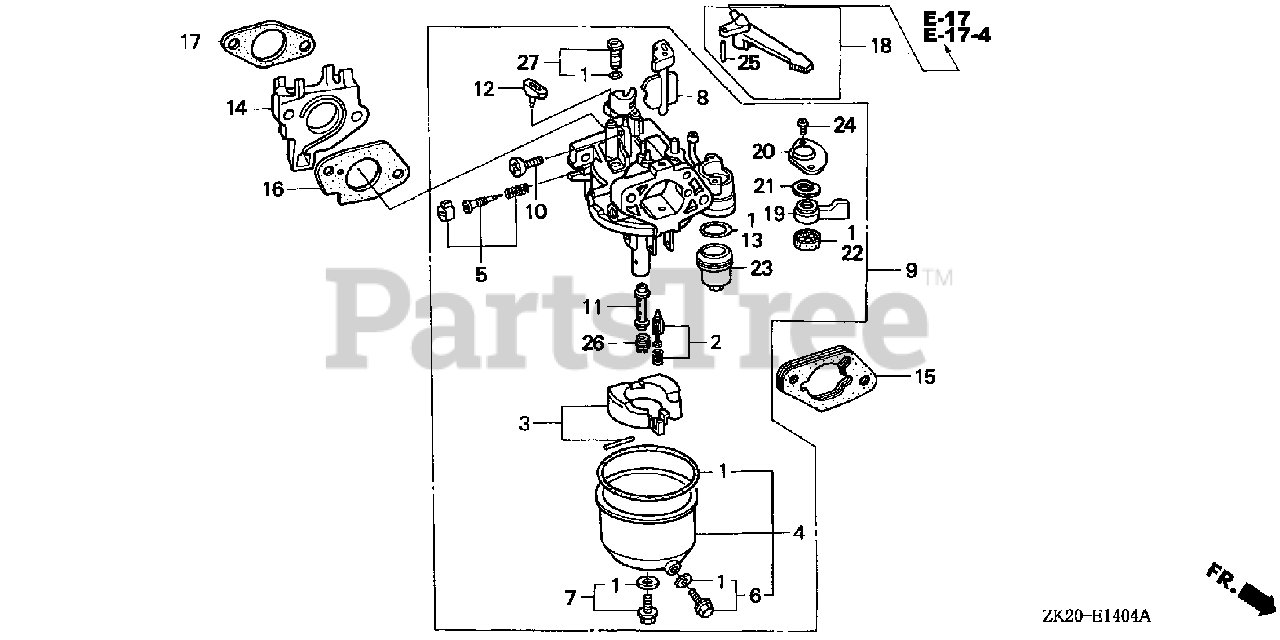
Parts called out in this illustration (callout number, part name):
1	GASKET SET
2	VALVE SET, FLOAT
3	FLOAT SET
4	CHAMBER SET, FLOAT
5	SCREW SET
6	SCREW SET, DRAIN
7	SCREW SET B
8	CHOKE SET
9	CARBURETOR ASSY. (BE70B B)
10	SCREW, THROTTLE STOP
11	NOZZLE, MAIN
12	COLLAR, SET
13	GASKET, FUEL STRAINER CUP
14	INSULATOR, CARBURETOR
15	SPACER, CARBURETOR
16	GASKET, CARBURETOR
17	GASKET, INSULATOR
18	LEVER, CHOKE (STD)
19	LEVER, VALVE
20	PLATE, LEVER SETTING
21	SPRING, VALVE LEVER
22	GASKET, VALVE
23	CUP, FUEL STRAINER
24	SCREW, PAN (3X6)
24	SCREW, PAN (3X8)
25	PIN, SPRING (2X12)
26	JET, MAIN (#82)
26	JET, MAIN (#85)
26	JET, MAIN (#88)
27	JET SET, PILOT (#40)
